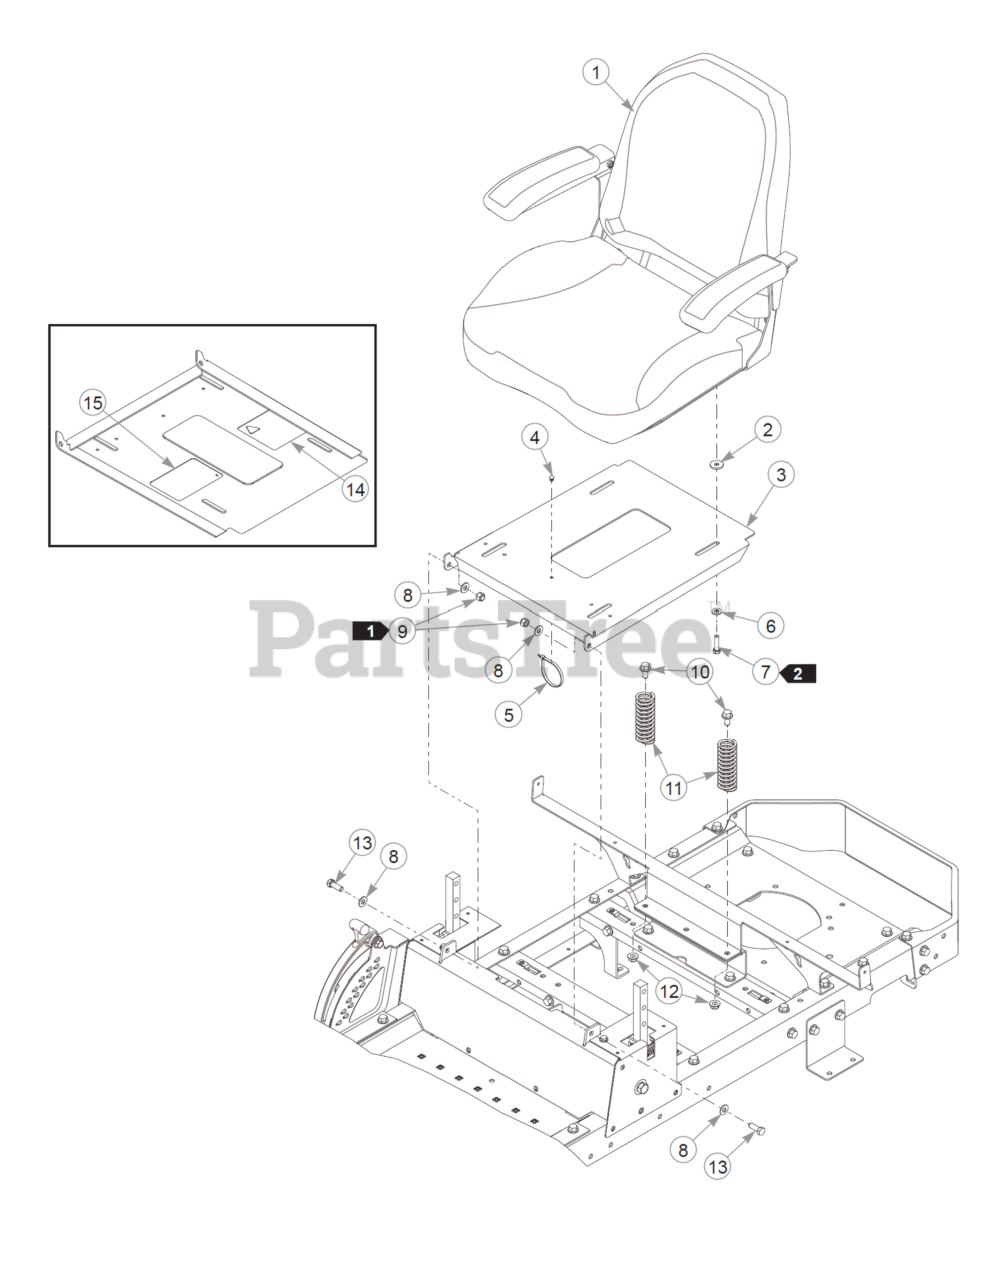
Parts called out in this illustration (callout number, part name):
1	BAG-SEWN ONLY 530 PUSH 20/BX
2	FW 0.344X1.00X.12 HD ZN
3	SVC, SEAT PAN
4	MOUNT, PUSH BUTTON
5	WIRE TIE, SMALL/SHORT
6	FW 0.343SAE
7	CS .312-18X1.250HXG5
8	FW 0.379X.82X.06 HD ZN
9	ASSEMBLY BLADE
10	CS .375-16X0.75 HXF G5ZN
11	SPRING,COMP 1.25X4.00X.
12	NT .375-16 FLKG5
13	CS .375-16X1.00 HX G5 ZN
14	DECAL, BELT ROUTING
15	DECAL, BATTERY WARNINGS
